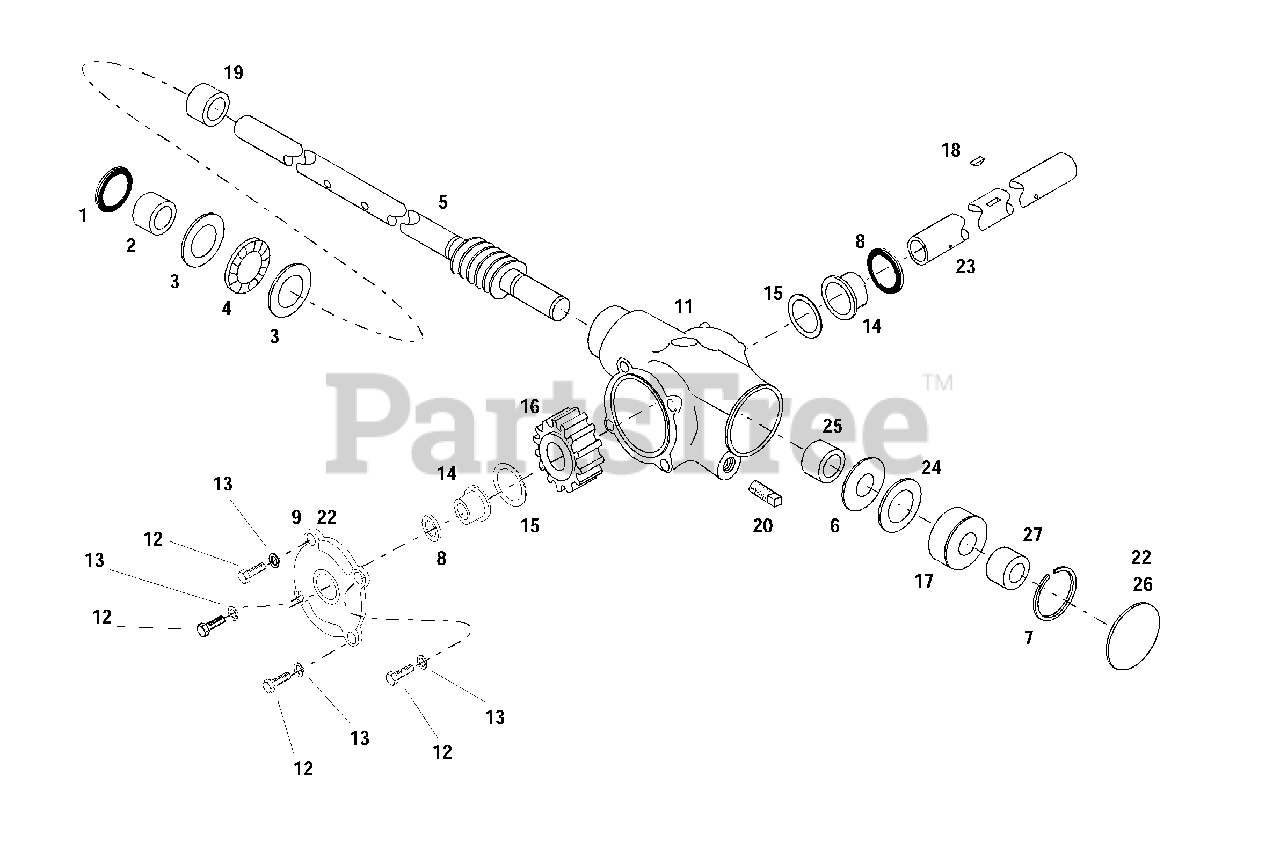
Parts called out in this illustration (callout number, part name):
2	Needle Bearing
3	Thrust Race
4	Roller Thrust Bearing
5	Impeller Shaft
6	Washer
7	Internal Retaining Ring
8	Oil Seal
9	Flanged Cover
11	Gear Case
12	Hex-Head Cap Screw, 1/4-20 x 5/8
13	Lock Washer, 1/4
14	Flange Bearing
15	Thrust Race
16	Worm Gear, 20T
17	Spacer
18	Woodruff Key, 1/4 x 7/8
20	Square Head Plug, 1/4-18 NPT
22	Sealant
23	Auger Shaft
24	Thrust Race
25	Spacer
26	Welch Plug
27	Needle Bearing
